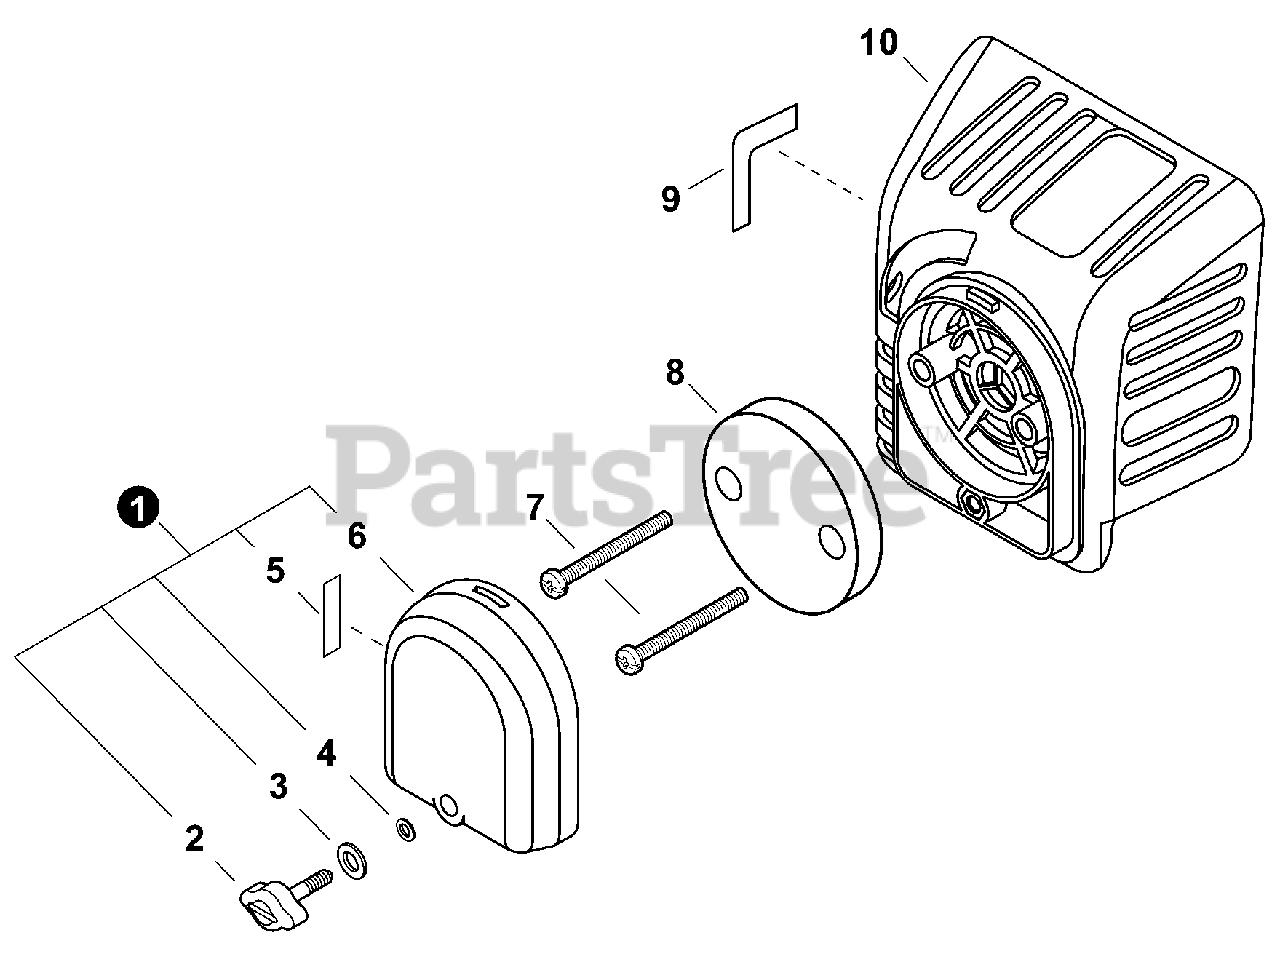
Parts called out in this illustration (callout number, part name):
1	COVER ASSY, AIR FILTER
2	THUMBSCREW
3	WASHER, CONE M6
4	O-RING
5	LABEL - CHOKE
6	COVER, AIR FILTER
7	SCREW M4x25
8	FILTER, AIR
9	LABEL - CARBURETOR
10	CASE, AIR FILTER
